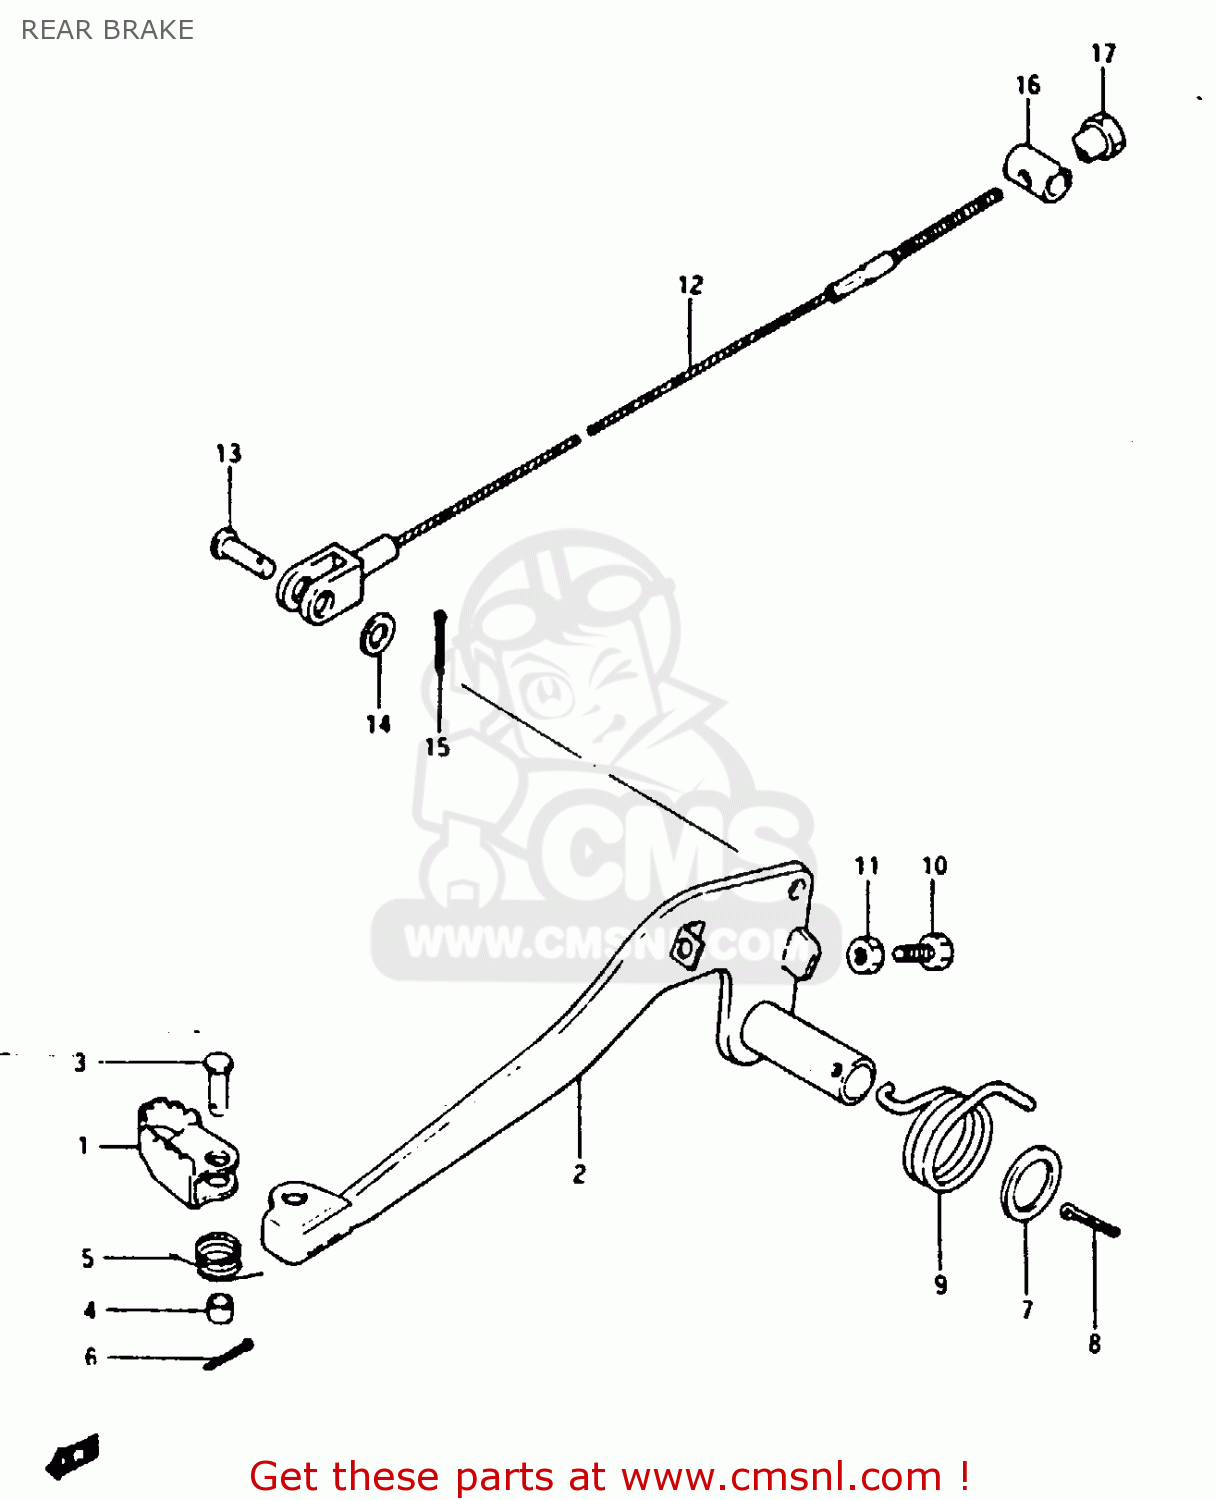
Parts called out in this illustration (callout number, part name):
1	PEDAL,BRAKE
2	ARM, BRAKE PEDAL
3	PIN
4	SPACER
5	SPRING
6	PIN
7	WASHER(15.5X26X2.3)
8	COTTER PIN
9	SPRING
10	SCREW(6X23)
11	NUT
12	CABLE,RR BRAKE
13	PIN(L:17.5)
14	WASHER
15	PIN 20X20
16	PIN
17	NUT (6MM)
